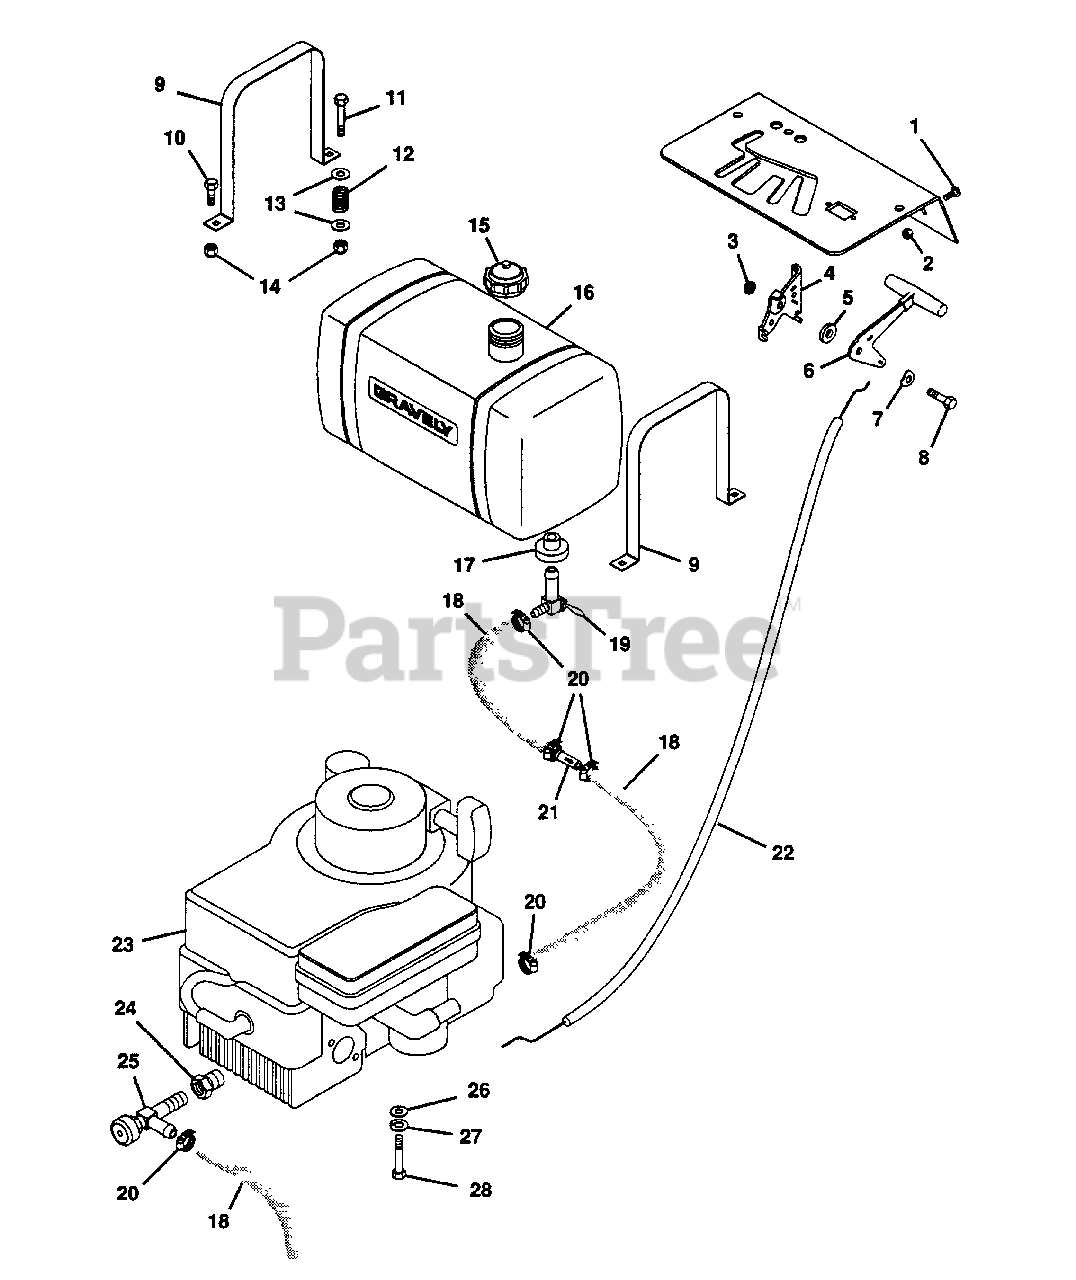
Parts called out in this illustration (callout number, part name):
1	SCREW, MACH. 10-32X.50 PHD
2	NUT, LOCK 10-32
3	NUT, LOCK 1/4-28
4	BRACKET, MOUNTING L.H.
5	WASHER, FRICTION
6	ASSEMBLY, KNOB AND LEVER
7	WASHER, SPRING
8	BOLT, HEX 1/4-28X.75
9	STRAP, FUEL TANK
10	BOLT, HEX 1/4-20X.625
11	BOLT, HEX 1/4-20X1.75
12	SPRING, COMP. 1X.78X338 LB/IN
13	WASHER, FLAT .281X.625X.065
14	NUT, LOCK 1/4-20
15	CAP, FUEL TANK
16	TANK, FUEL
17	BUSH., FLG. .375X1.06X.625 RB.
18	LINE, FUEL
19	VALVE, BALL SHUT-OFF
20	CLAMP, HOSE
25	COCK, OIL DRAIN
26	WASHER, FLAT .344X.688X.065
27	WASHER, LOCK 5/16 REG.
28	BOLT, HEX M8X1.25 30MM
